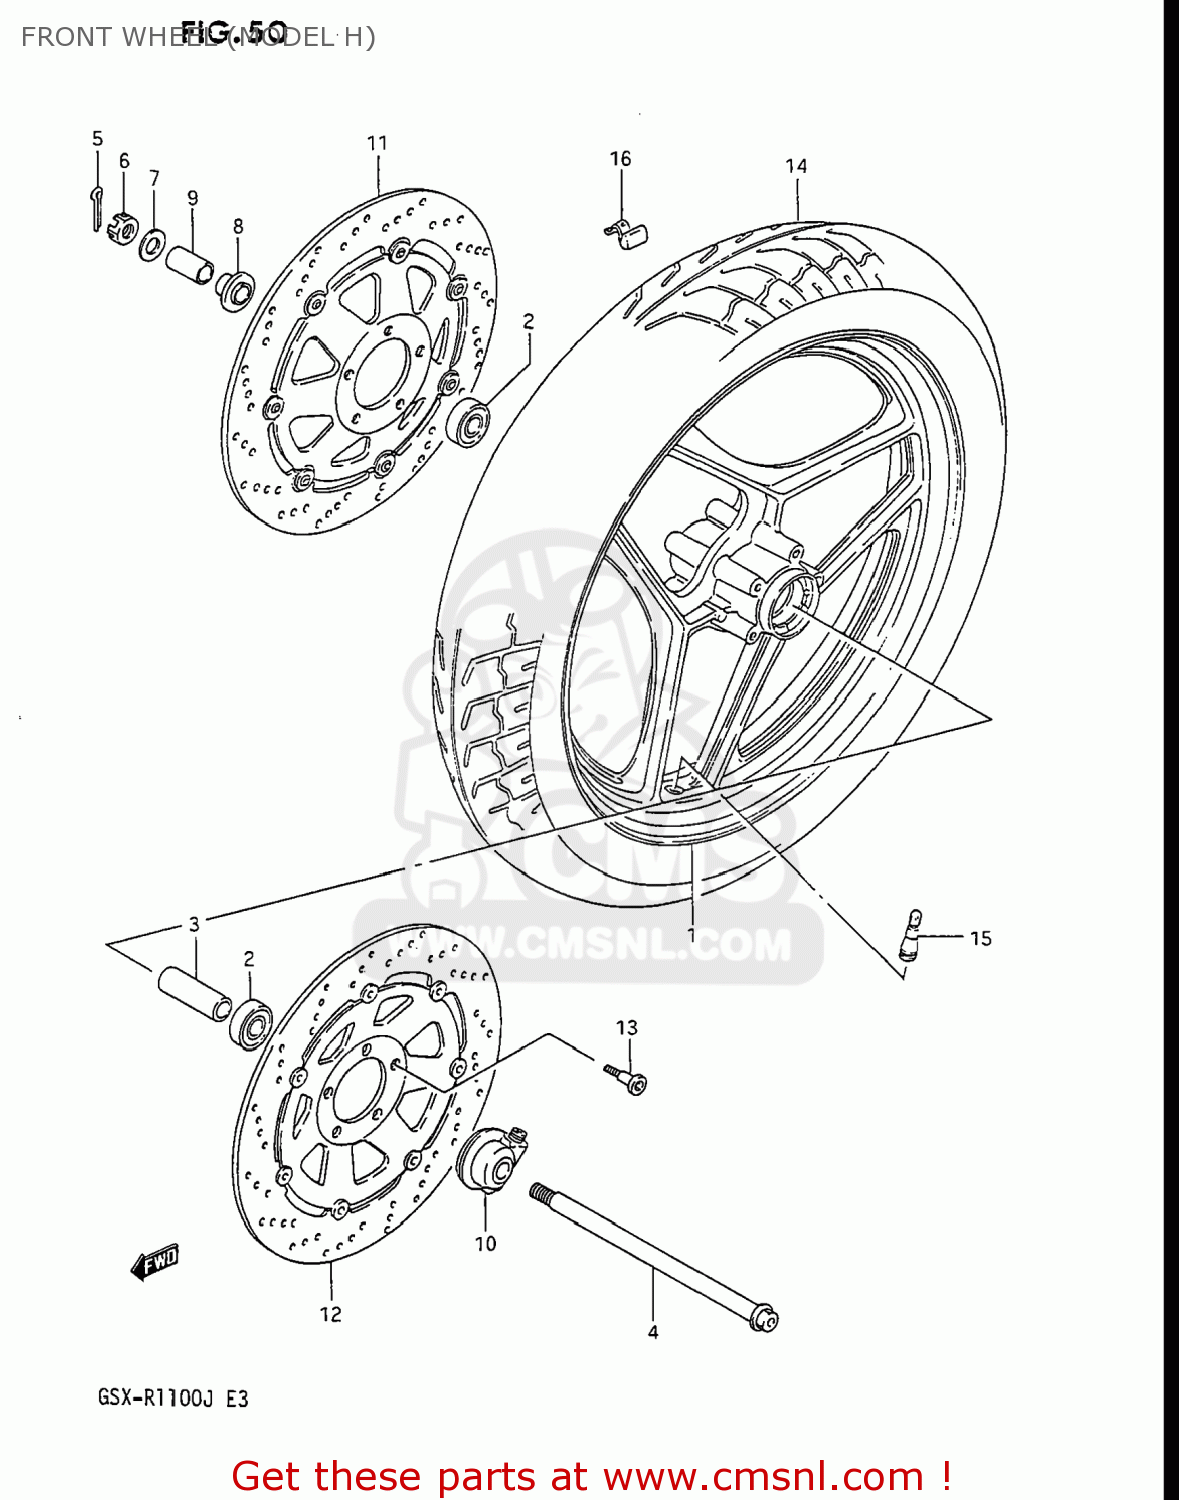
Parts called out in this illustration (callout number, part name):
1	WHEEL,FRONT (MT2.75X18)
2	BEARING(17X42X13)
3	SPACER (17.3X24X78)
4	AXLE,FRONT
5	PIN,COTTER
6	NUT
7	WASHER
8	SPACER,FR HUB,R
9	SPACER,FR AXLE
10	BOX ASSEMBLY,SPEEDOMETER GEAR
11	DISC,BRAKE
12	DISC,BRAKE
13	BOLT
14	TIRE,TUBELESS 110/80V
15	VALVE,TIRE
16	BALANCER,WHEEL
